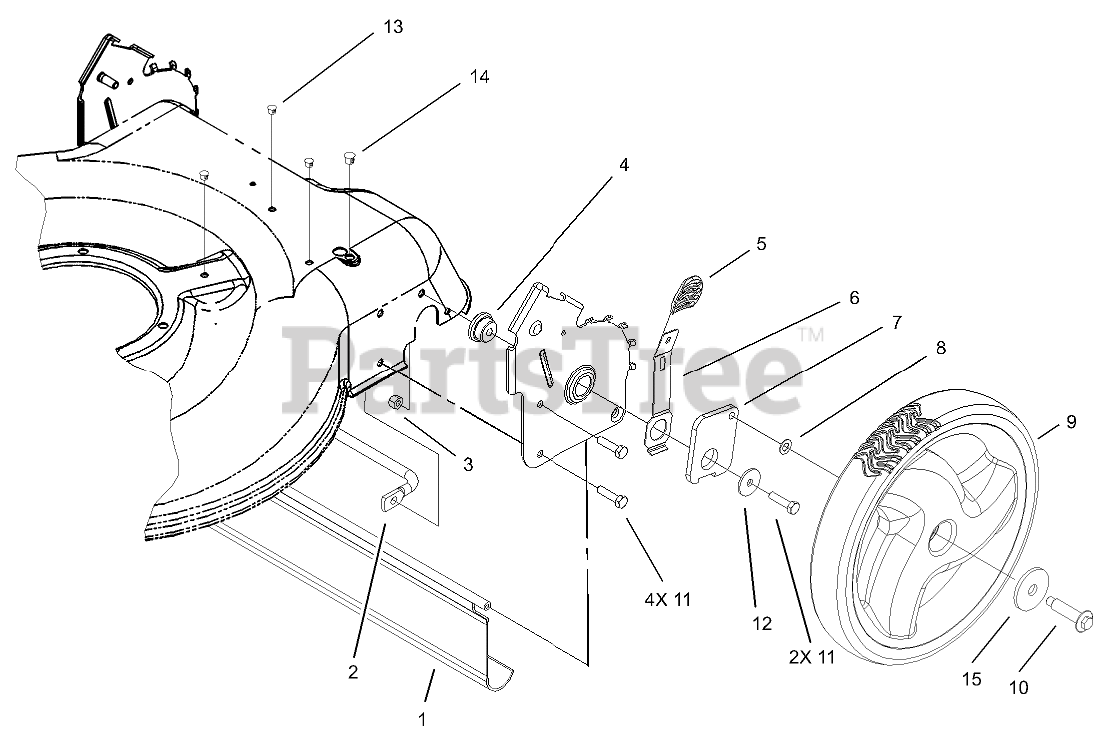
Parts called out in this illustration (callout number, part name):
1	Shield-Trailing
2	BRACE-PLATE, HOC
3	NUT-LOCK, NI
4	Bushing-Mount, HOC
5	Knob-Lever, HOC
6	Arm-Spring
7	Arm-Pivot, Rear
8	WASHER
9	Wheel ASM
10	BOLT-SHOULDER
11	SCREW-HH
12	Washer-Flat
13	Plug-Dome
14	Plug-Dome
15	WASHER-PLAIN
